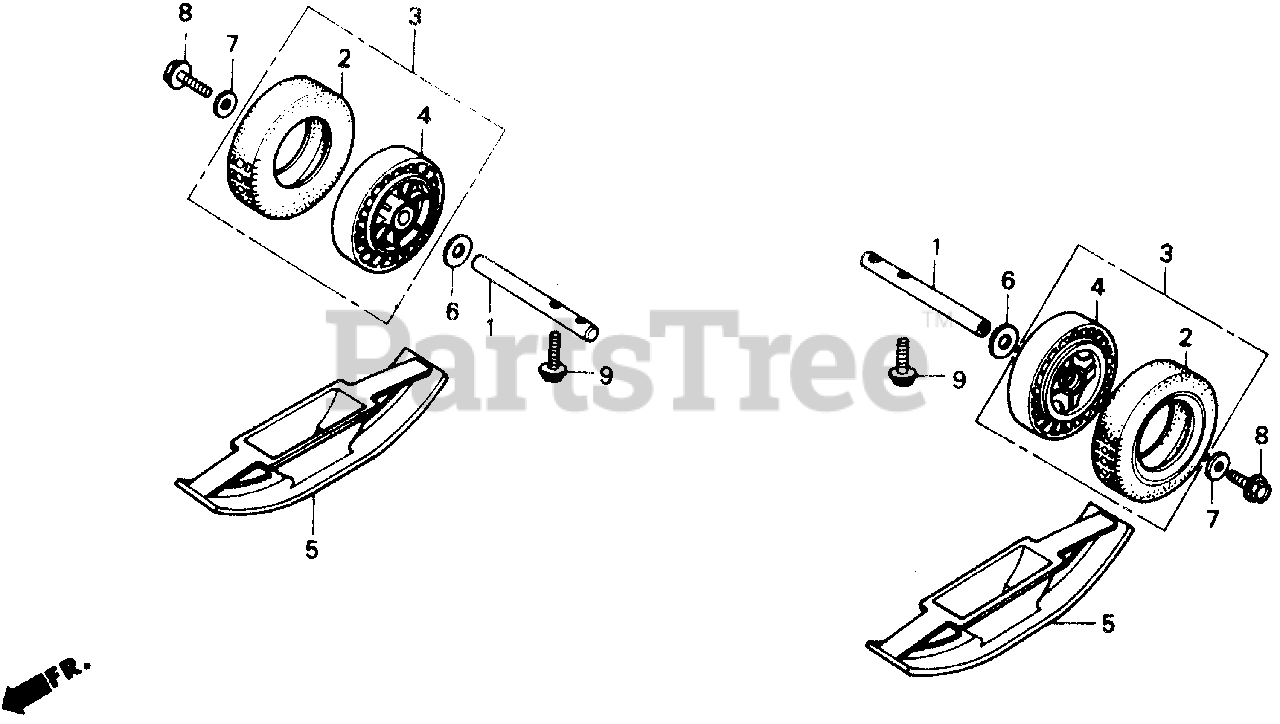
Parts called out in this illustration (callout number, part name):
1	SHAFT, WHEEL
2	TIRE, FR. (7INCH)
3	WHEEL ASSY.
3	WHEEL ASSY. (NOT AVAILABLE)
4	HUB, WHEEL *NH31* (MCKINLEY WHITE)
6	WASHER (15MM)
7	WASHER (8MM)
7	WASHER, PLAIN (8MM)
8	BOLT, FLANGE (8X12)
9	BOLT, FLANGE (8X20)
